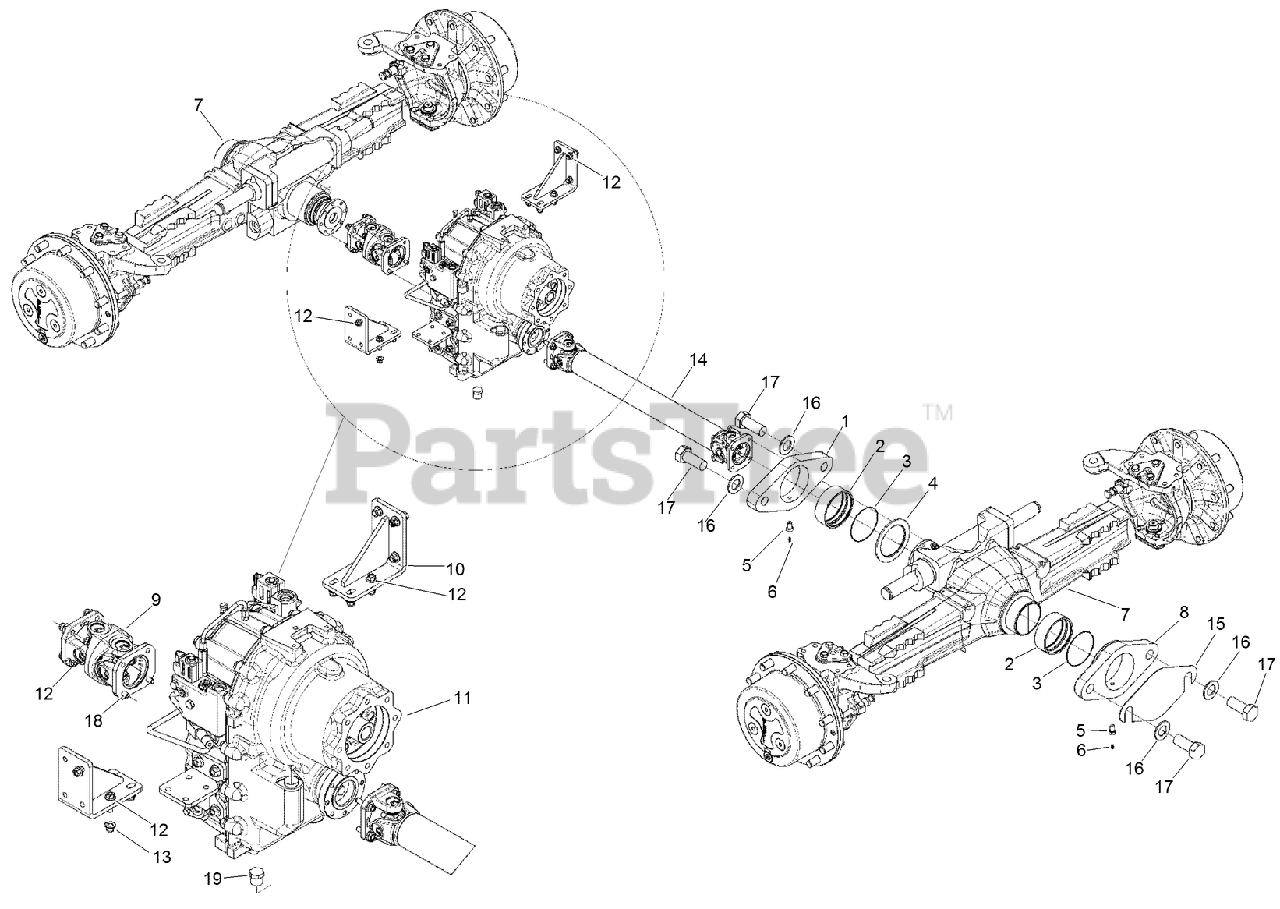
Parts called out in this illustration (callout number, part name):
1	TRUNION - Axle Pivot, Rear
2	BUSHING-PIVOT
4	WASHER - Thrust
5	ADAPTER-LOCATING
6	FITTING - STR Grease 3/16
8	TRUNION - Axle Pivot, Front
9	JOINT - Constant Velocity
10	MOUNT - Transmission
11	TRANSMISSION - 2 Speed Powershift
12	SCREW-HHF
13	NUT-FLANGE, NYLOCK
14	SHAFT ASSEMBLY - Front Axle Drive
15	SHIM-MOUNT, AXLE
18	SCREW-FLANGE
19	PLUG-HYD
